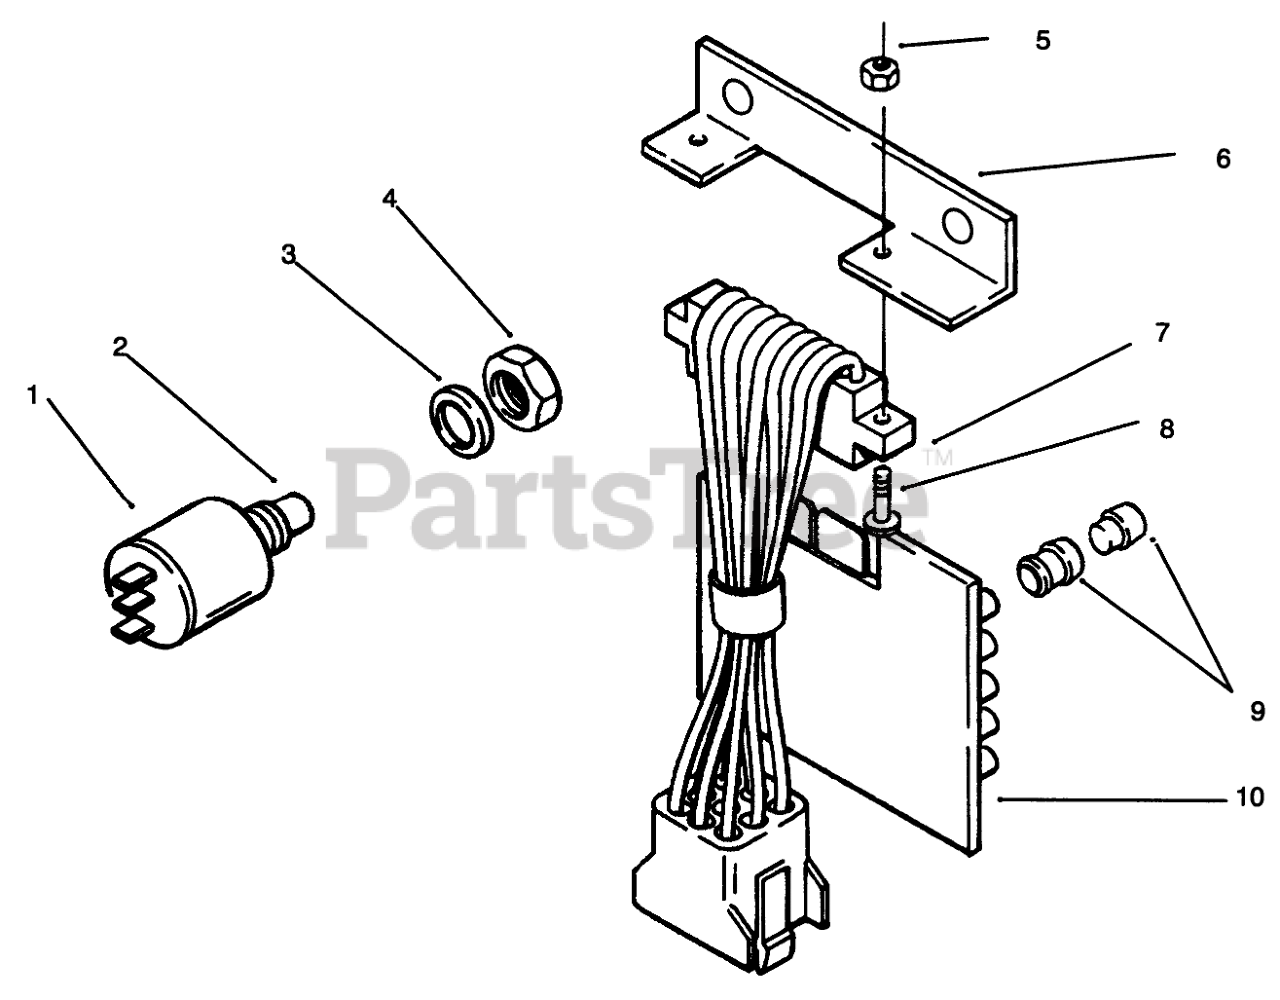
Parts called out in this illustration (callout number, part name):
1	Test Switch (Incl. Ref. #2-4)
2	BUTTON F/W 116796
3	Washer
4	NUT F/W 116796
4	Boot
5	NUT-HEX
6	BRACKET
7	P.C. BOARD HARNESS
8	Screw
9	ASSY LENS & BUSHING
10	Board-Pc
